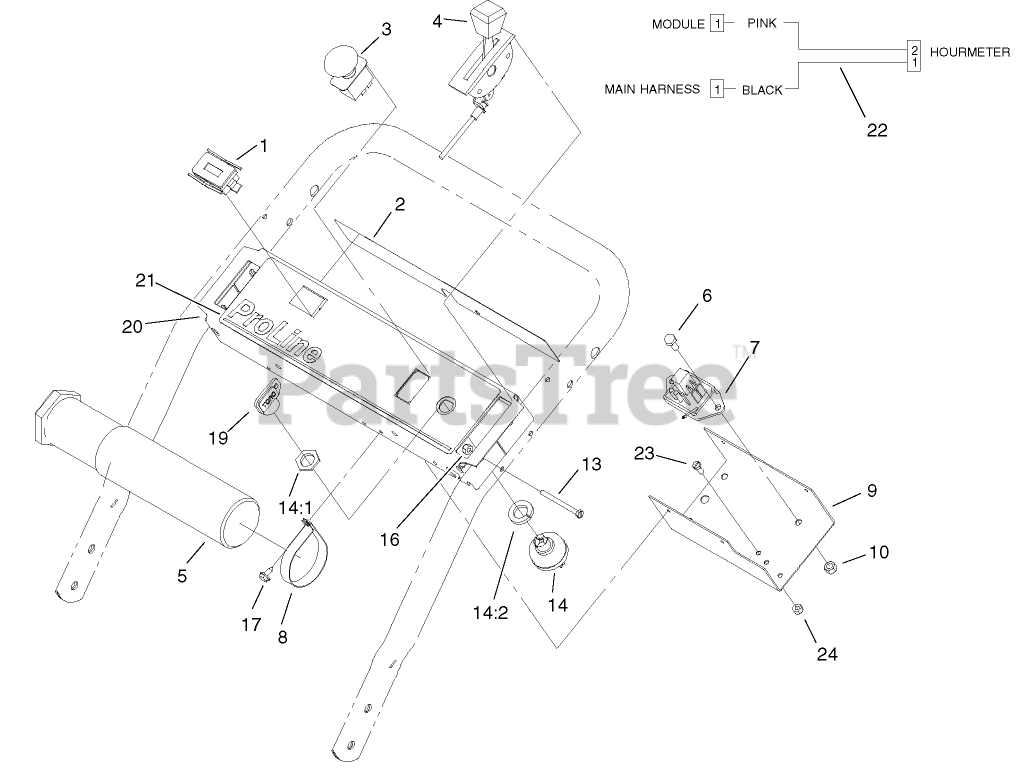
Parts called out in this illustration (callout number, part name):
1	HOURMETER
2	DECAL-WARNING
3	SWITCH-PTO
4	CONTROL-THROTTLE
5	TUBE-MANUAL
6	SCREW-HH
7	MODULE-DELAY
8	CLAMP-R
9	PANEL-BOTTOM
10	NUT-LOCK, NI
13	SCREW-SHH
14	SWITCH-ON / OFF
14:1	NUT-HH
14:2	WASHER-TOOTH, INTERNAL
16	NUT-LOCK, NI
17	SCREW-HWHTF
19	KEY-IGNITION
20	PANEL-CONTROL
21	DECAL-PANEL, CONTROL
23	SCREW-SHH
24	NUT-LOCK, NI
